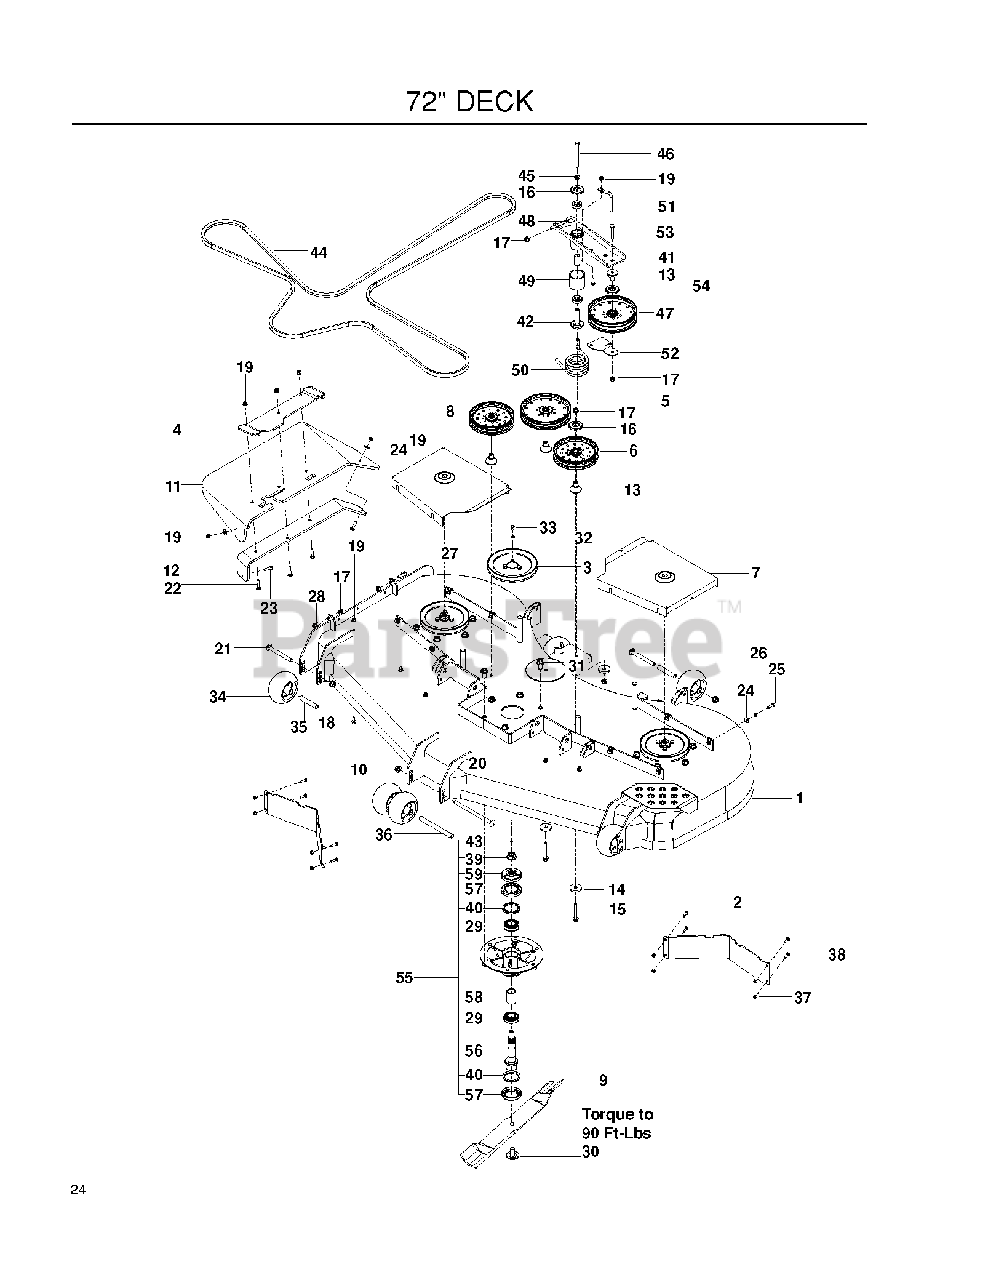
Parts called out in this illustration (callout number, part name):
1	DECK.FAB.W/DECALS.72.BLUE.DIXO
2	Diverter Deck Baffle, 72"
3	PULLEY - 7.50
4	BRKT - CHUTE MTG BLACK
5	PULLEY - 7" NARROW
6	PULLEY IDLER, 6" NARROW
7	SHIELD, 72 RT
8	SHIELD BELT LH 72 BLUE
9	BLADE OEM - 25"
10	NUT, 1/2-13 HEX FLG NYLOC ZD
11	CHUTE, DISCHARGE 60-72
12	BRKT - CHUTE SUPPORT BLACK
13	BEARING, IDLER ARM
14	SPINDLE WASHER
15	HHFS 3/8-16 X 2 3/4
16	DUST SHIELD
17	NUT 3/8-16 HEX FLG NYLOC ZD
18	HHFS 5/16-18 X 3/4
19	5/16-18 NYLOC FLANGE NUT
20	RHSNB 1/2-13 X 8 GR5 ZD
21	RHSNB 1/2-13 X 4.75 GR5 ZD
22	RHSNB 5/16-18 X 1-1/2 GR 5 ZD
23	BOLT, CARRIAGE 5/16X1-1/4
24	WASHER 5/16 FLAT
25	HCS 5/16C X 1
26	WASHER 5/16 LOCK
27	U-CLIP 5/16-18 NUT RETAINER
28	HHFS 3/8-16 X 1 GRD 5 ZD
29	BEARING - 206KRR8
30	BLADE BOLT/WASHER
31	HHFS 1/2-13 X 1 GR5 ZD
32	WASH 5/16 DISC SPRING ZD
33	HCS 5/16-18 X 1/2 GR 5 ZD
34	ROLLER, GAUGE .635 BORN
35	TUBE, ROLLER AXLE
36	TUBE, ROLLER AXLE LONG
37	NUT 1/4-20 NYLOC
38	RHSNB, 1/4-20 X 1, GR5
39	NUT FLANGE 3/4-16
40	V-RING, 55MM
41	Idler Arm Assembly, PZ
42	BEARING, IDLER PIVOT
43	ZERK
44	BELT, "B", 201
45	WASHER, 3/8 THICK
46	HCS 3/8-16 X 4-1/2 GR 8 ZD
47	PULLEY - IDLER 7"
48	Eyebolt, 3/8 X 4"
49	Idler Pivot Spacer
50	SPRING, TORSION, IDLER
51	Belt Keeper
52	BELT.GUIDE.BLACK
53	CARRIAGE BOLT 3/8-16 X
54	RHSSNB 5/16C X 1.0
55	SPINDLE ASM. 10"
56	SHAFT - SPINDLE
57	CUP - DEBRIS
58	SPACER - BEARING
59	HUB - PULLEY
